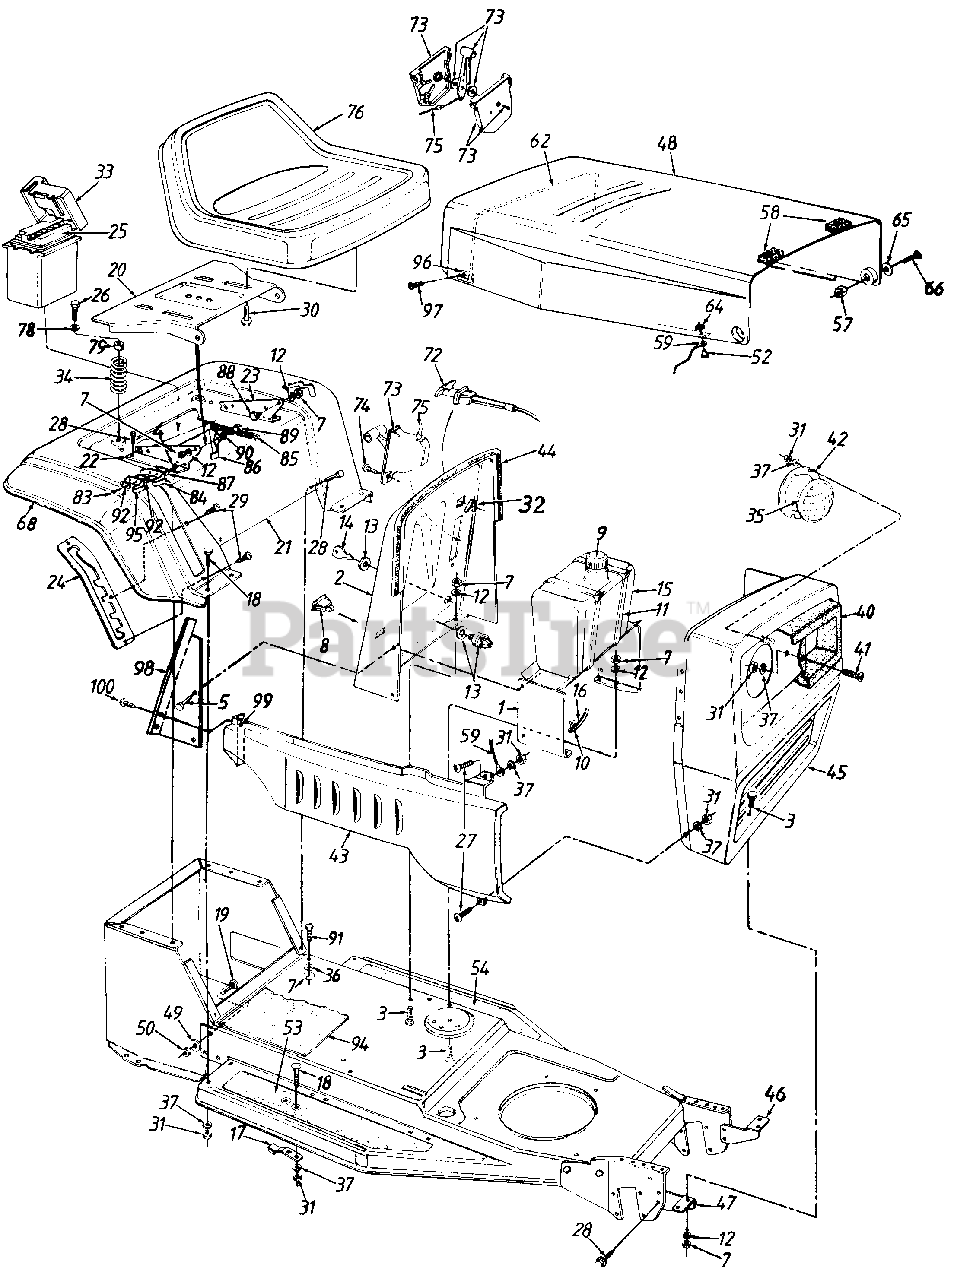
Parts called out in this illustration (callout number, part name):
1	Dash Panel Support Brkt.
4	External L-Wash. 114" I.D.
5	Hex AB-Tap Scr. 1/4 x .62"
7	Hex Nut 5/16-18 Thd.
8	Light Switch
9	Gas Cap
11	Cable Tie
12	L-Wash. 5/16" I.D.
13	Ignition Switch
14	Ignition Key
15	Fuel Tank
16	Gas Line-15" Lg.
17	Blade Brake Ass'y.
18	Carriage Bolt 1/4-20 x .62"
19	Ribbed Neck Bolt 3/8-24 x .8"
20	Seat Pivot Brkt.
25	Battery
26	Hex Self-Tap Screw 5/6-18 x 1.25" Lg.
27	Truss Mach. Scr. 1/4-20 x .5" Lg
28	Hex AB-Tap Scr. 5/16 x .75" Lg
29	Torx Mach. AB-Tap Scr. 1/4 x .62" Lg.
30	Hex Self-Tap Scr. 3/8-16 x .75" Lg.
31	Hex Nut 1/4-20 Thd.
32	Retainer Clip
33	Battery Box w/Cover
34	Compression Spring
35	Headlight
36	Bell-Wash. 5116" I.D.
37	L-Wash. 1/4" I.D.
41	C-Sunk Mach. Scr. 1/4-20 x 1.5"
42	Headlight Retainer
43	Side Panel-R.H.
44	Trim Strip 31" Lg.
47	Grille Mtg. Brkt.-R.H.
50	Hex L-Nut 3/8-24 Thd.
52	Truss Mach. Scr. #10-24 x .5" Lg.
53	Foot Pad-R.H.
54	Foot Pad-L.H.
57	Lock Nut 1/4-28 Thd.
64	Hex Sems Nut #10-24 Thd.
65	Spr. Wash. .39" I.D. x .62" O.D.
66	Shld. Bolt
68	Trim Strip 81" Lg.
72	Choke Control
73	Throttle Control Box
74	Truss AB-Tap Scr. #10 x .5"
75	Throttle Wire
76	Seat Assembly
78	Flat Wash. .344" I.D. x .88" O.D.
83	Hex Tap Scr. #8 x .5" Lg.
84	Safety Switch
85	Ext. Spring 5.31" Lg.
86	Seat Lift Brkt.
87	Insulator Boss Plate
88	Shld. Bolt 437" Dia. x .162" Lg.
89	Shld. Bolt .437" Dia. x .268" Lg.
90	Spr. Wash. 445" l.D. x .75" O.D.
91	Hex Wash. Hd. Scr. 5/16-18 x .62" Lg.
92	Insulator Plate
94	Center Foot Pad
95	Safety Switch
96	Hood Spring Retainer
97	Oval Hd. Self-Tap Scr. .5" Lg.
98	Side Panel Mtg. Brkt.-R.H.
99	Speed Nut #10-24 Thd.
100	Truss Mach. B-Tap Scr. #10 x .5" La.
